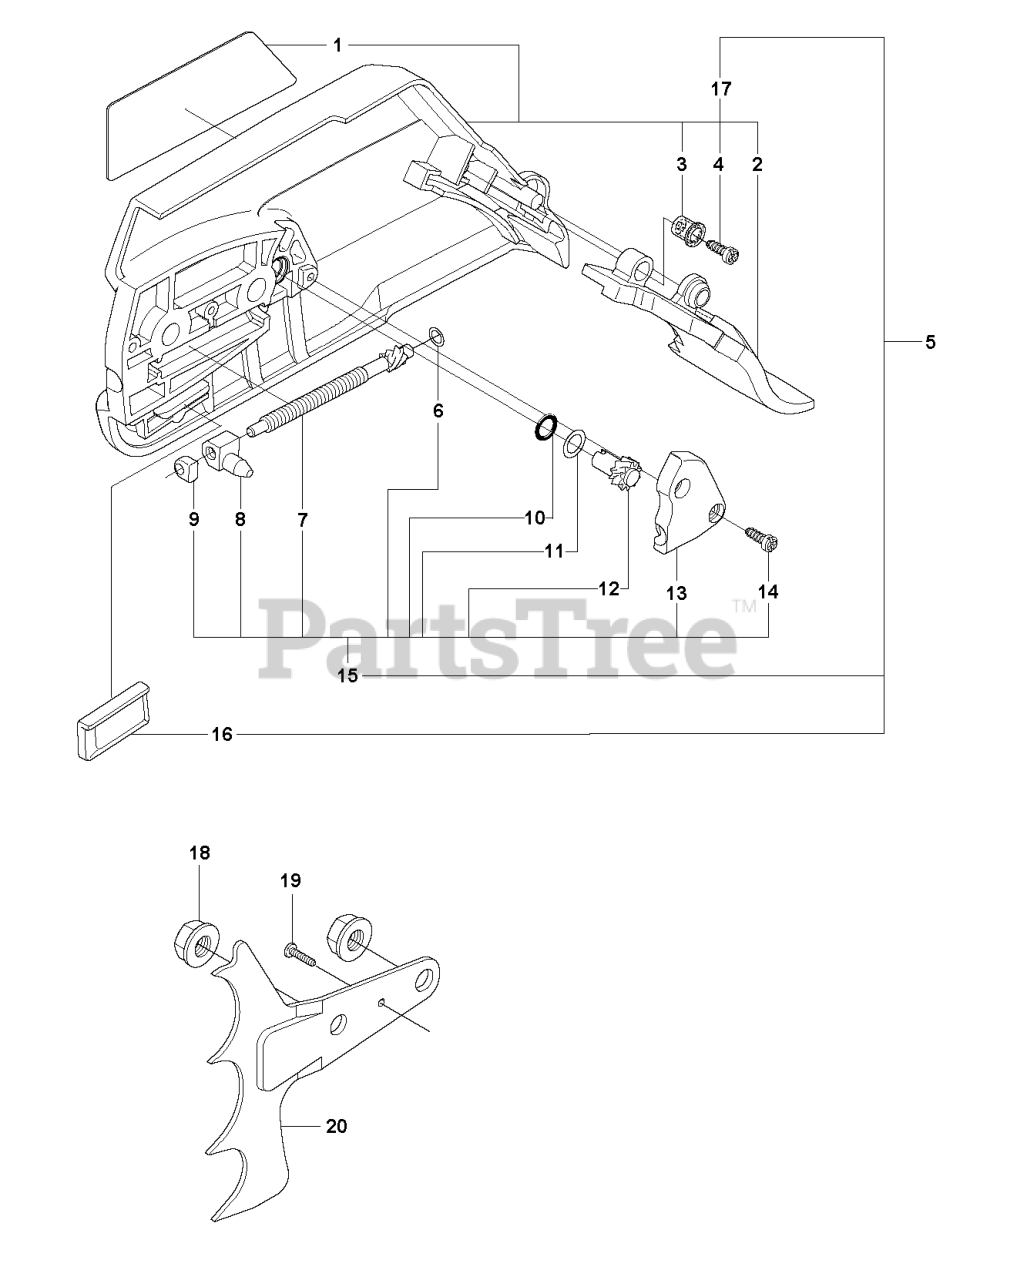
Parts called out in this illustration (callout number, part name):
5	CHAIN BRAKE COVER
7	WORM SCREW / ADJUSTER
12	WORM WHEEL
15	KIT-CHAIN TENSIONER
16	CHAIN GUIDE
17	CHAIN BRAKE COVER
18	NUT M8 FLANGE
20	SPIKE OUTER
